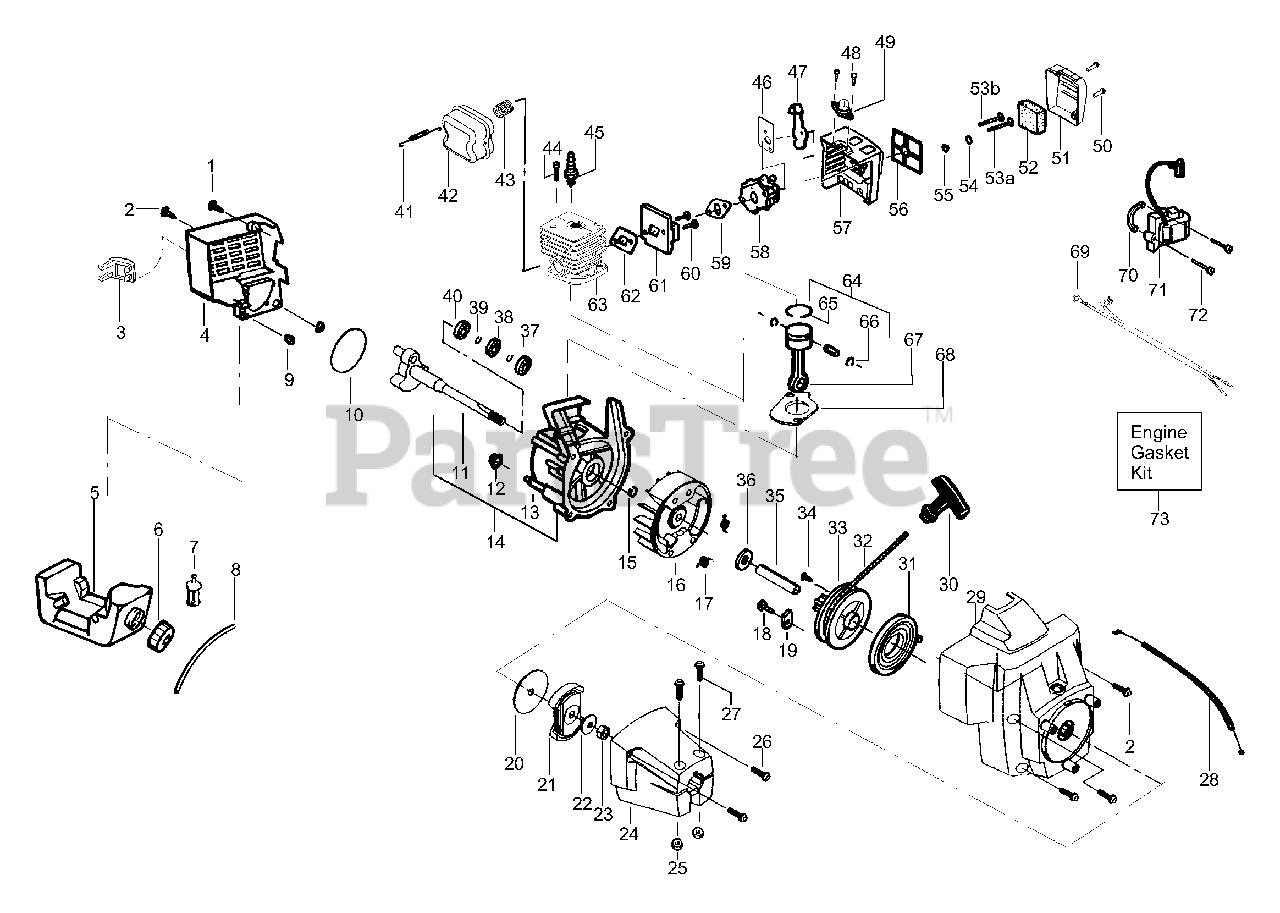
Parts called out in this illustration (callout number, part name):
2	Screw
3	Guard-Muffler
5	Fuel Tank Ass'y.
6	Fuel Cap Ass'y.
7	Fuel Pickup Ass'y.
8	Kit - Fuel Line
9	Isolator-Shroud
10	O-Ring-C'case/Shroud
11	Crankshaft Ass'y.
12	Support-Carb. adapter
13	Crankcase Ass'y.
14	C'case & C'shaft Assy.
15	Retainer (C'shaft)
16	Flywheel Ass'y
17	Spring - Starter Dog
19	Retainer
20	Washer-Clutch
21	Clutch Ass'y.
22	Washer-Flat
24	Clutch Hsg. Ass'y.
28	Throttle Cable Ass'y.
29	Fan Housing
30	Starter Handle
31	Starter Spring
32	Rope Kit
33	Kit-Starter Pulley
35	Spacer-Flywheel
37	Outer Bearing
38	C'case Seal
39	Retaining Ring-C'case
40	Inner Bearing
41	Muffler Spring
42	Muffler Kit
43	Screen-Spark Arrestor
45	Spark Plug (RCJ-8Y)
46	Choke Plate
47	Choke Shutter
49	Bulb Ass'y.
51	Air Filter Cover
52	Air Filter Foam
53A	Carb Screw
53B	Carb Screw
54	Choke Spacer
56	Plate-Filter Support
58	Carburetor Ass'y.
59	Gasket-Carburetor
61	Carb. Adaptor Kit
62	Gasket-Cyl/Carb Adpt
63	Cylinder Kit
64	Piston Kit
65	Piston Ring
66	Piston Pin Retainer
67	Connecting Rod Ass'y.
68	Gasket-Cylinder
69	Ass'y.-Switch Wire
70	Spacer-Ign. Module
71	Ignition Module
73	Engine Gasket Kit
